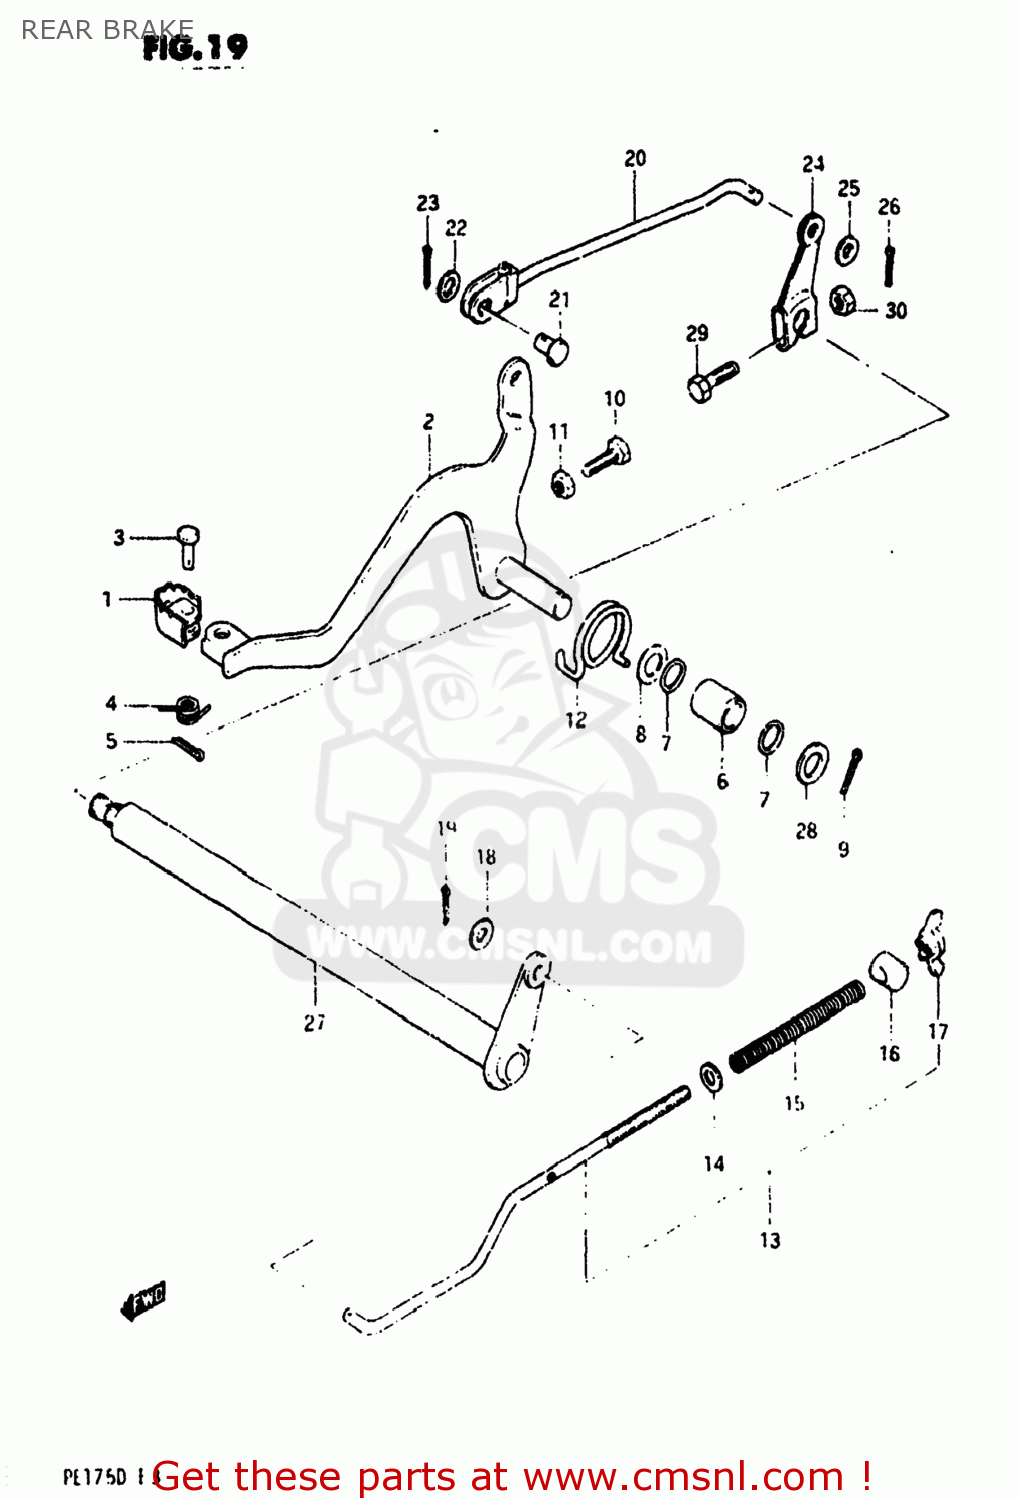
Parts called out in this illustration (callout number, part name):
1	PEDAL,BRAKE
2	ARM,BRAKE PEDAL
3	PIN
4	SPRING
5	PIN
6	BUSHING
7	O RING(D:2.2,ID:11.8)
8	WASHER
9	PIN 30X20
10	BOLT(6X23)
11	NUT
12	SPRING
13	ROD ASSEMBLY,REAR BRAKE,REAR
14	WASHER
15	SPRING
16	PIN
17	NUT
18	WASHER
19	PIN 20X20
20	ROD ASSEMBLY,REAR BRAKE FRONT
21	PIN(L:13.5)
22	WASHER
23	PIN 20X20
24	ARM,REAR BRAKE ROD,OUTER
25	WASHER
26	PIN 20X20
27	ARM,REAR BRAKE ROD
28	WASHER(12.1X30X2.3)
29	BOLT
30	NUT
